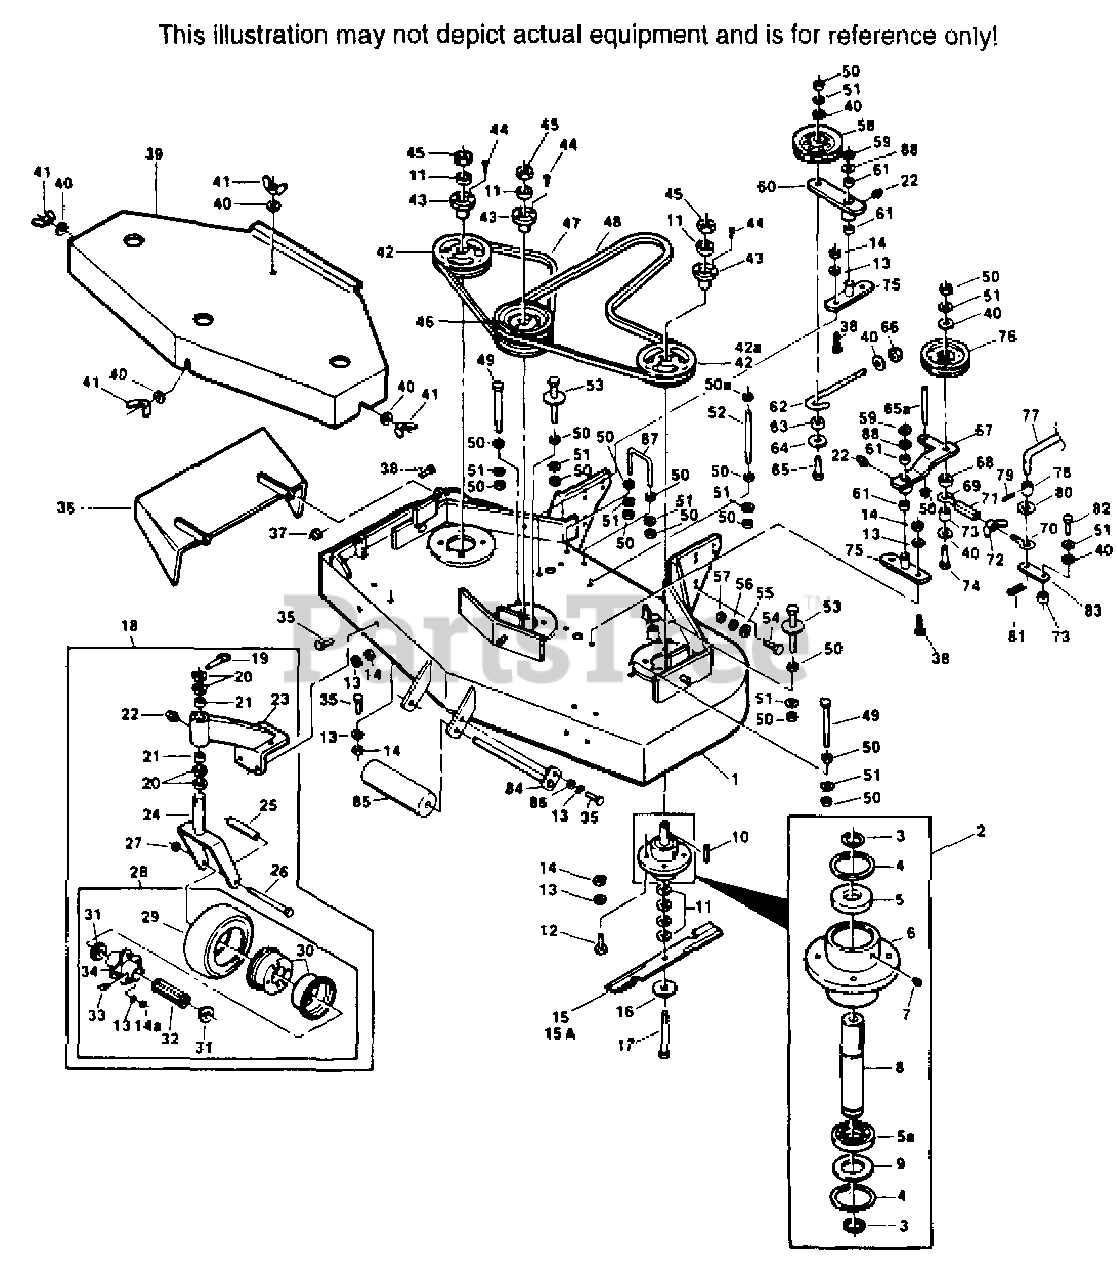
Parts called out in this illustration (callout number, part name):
2	CUTTER SPINDLE ASSY.(INCL. 3-9)
3	RETAINING RING, 1" EXT.-INVERTED
4	RETAINING RING, 2-7/16" INT. BASIC
5	BEARING, CUTTER SPINDLE UPPER
5A	BEARING, CUTTER SPINDLE LOWER
6	SPINDLE HOUSING
7	GREASE FITTING STR. 5/16 SERR.
8	SPINDLE, CUTTER BLADE
9	WASHER, 1-5/16 X 2-7/16 X 16 GA.
10	KEY, 1/4 X 1/4 X 2
11	SPACER, CUTTER BLADE
16	FLAT WASHER, 5/8" W
17	HEX HD BOLT, 5/8-11 X 9-1/2"
18	CASTER ASSY, COMP.(INCL. 19-28)
19	QUICK PIN
20	SPACER, CASTER YOKE, 1/2" THICK
21	BRONZE BEARING
22	GREASE FITTING, STR., 1/4-28
23	SUPPORT ASSY.(INCL. 21-22)
24	CASTER YOKE
25	SLEEVE, CASTER WHEEL BEARING
26	HEX HD BOLT, 1/2-13 X 5-1/2
28	WHEEL ASSY.(INCL. 13-14, 29-34)
29	TIRE ONLY, CASTER WHEEL
30	RIM PAIR, CASTER WHEEL
31	RETAINER, BEARING, CASTER WHEEL
32	ROLLER BEARING, CASTER WHEEL
33	GREASE FITTING 45' 1/4-28
34	HUB ASSY.(INCL BOLTS)
36	DISCHARGE CHUTE
37	HEX NUT, 5/16-18 ELASTIC STOP
40	WASHER, 25/64 X 15/16 X 12 GA.
41	WING NUT, 3/8-16
42	PULLEY(INCL. 43-44)
43	TAPERED HUB
46	PULLEY, DOUBLE(INCL. 43-44)
50A	HEX NUT, 3/8-16, CENTERLOCK
52	SUPPORT, BELT COVER
53	BELT GUIDE
55	WASHER, 15/32 X 59/64 X 16 GA.
58	IDLER PULLEY, "V" GROOVE
59	RETAINING RING, 3/4" EXT. "E"
60	IDLER ARM ASSY.(INCL. 22 & 61)
61	BRONZE BEARING
62	J ROD, IDLER PULL
63	SPACER, J PULL ROD
64	WASHER, 3/8 X 1-1/2 X 16 GA.
66	HEX NUT, 3/8-16 ELASTIC STOP
67	IDLER ARM(INCL. 22 & 61)
68	SPACER
69	EYEBOLT,LH
70	EYEBOLT, RH
71	TURNBUCKLE
72	WING NUT, 5/16-18
73	SLEEVE, CAM CLUTCH
75	IDLER PIVOT
76	IDLER PULLEY, BELT CLUTCH
77	BLADE CLUTCH ROD, LOWER
78	SLEEVE, CLUTCH ROD
80	WASHER, 33/64 X 1 X 16 GA.
81	HAIR PIN, LARGE
83	CAM LINK
87	BELT GUIDE
